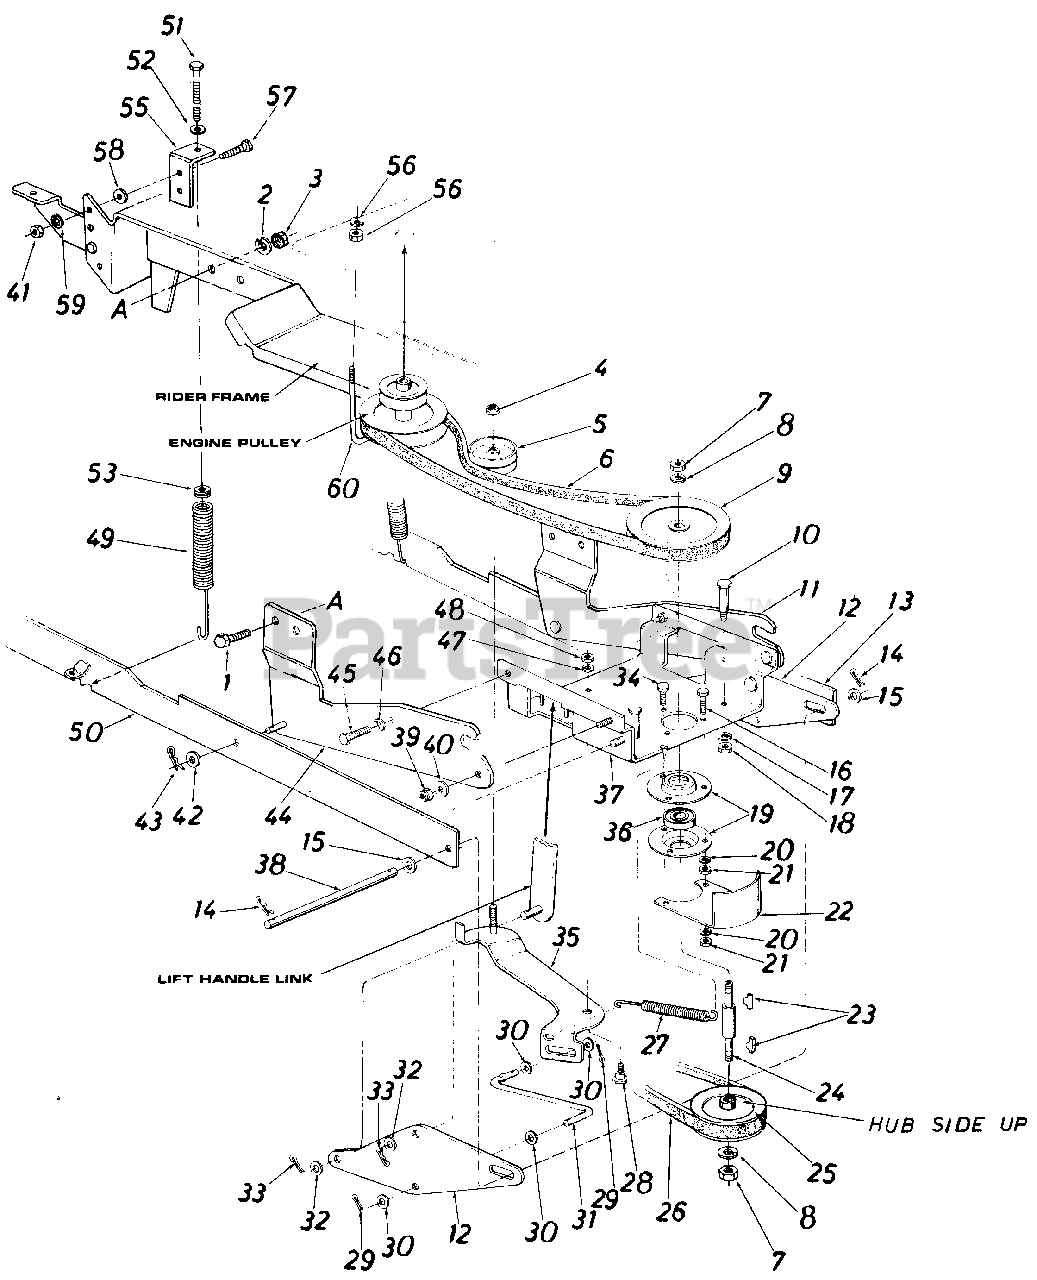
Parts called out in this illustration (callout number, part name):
1	Hex Scr. 1/4-28 x .75" Lg. Grade 5
2	L-Wash. 1/4" Scr.*
3	Hex Nut 1/4-2 Thd.*
4	Hex Ins. Jam Nut 3/8-24 Thd.
5	Flat Idler 3.25" O.D.
6	"V"-Belt 1/2 x 49" Lg.
7	Hex Jam Nut 5/8-11 Thd.
8	L-Wash. 5/8" I.D.*
9	6.50" O.D. x 5/8 Pulley
10	ShoulderScrew
11	Channel Supporting Brkt.-R.H.
12	Linkage Brkt.
13	Linkage Arm Ass'y. R. H.
14	Intern. Cotter Pin .500" Dia.*
15	Fl.-Wash.
16	Hex Scr. 5/16-18 x 1.25" Lg. *
17	L.-Wash. 3/8" Scr.*
18	Hex Nut 3/8-16 Thd.*
19	Bearing Housing
20	L.-Wash. 5/16" Scr.*
21	Hex Nut 5/16-18 Thd.*
24	Pulley Spindle
25	4.00 O.D. x 5/8 Pulley
26	"V"-Belt 1/2 x 85.2" Lg.
27	Extension Spring
28	Shoulder Screw
29	Cotter Pin 3/32" Dia. x 1.00*
30	F l-Wash.
31	Control Rod
32	Fl-Wash.
33	Inter. Cotter Pin .500" Dia.*
34	Hex Sems Scr. 5/16-18 x 1.0" Lg.
35	Clutch Idler Brkt. Ass'y.
36	Ball Bearing
37	Channel Ass'y.
38	Lift Handle Shaft
39	Hex Ins. L-Nut 3/8-16 Thd.
40	F l.-Wash.
41	Hex Nut 1/4-20 Thd.*
42	F l.-Wash.
43	Intern. Cotter Pin .500" Dia.*
44	Channel Supporting Brkt.-L.H.
45	Hex Scr. 3/8-16 x 1.00" Lg. *
46	L.-Wash. 3/8" Scr.*
47	L.-Wash. 5/16" Scr.*
48	Hex Nut 5/16-18 Thd.*
49	Helper Spring
50	Linkage Arm Ass'y.-L.H.
51	Hex Scr. 5/16-18 x 2.0" Lg. Special
52	Fl.-Wash. 5/16" Scr.*
53	Spring Insert
57	Hex Bolt 1/4-20 x .75" Lg. *
58	Fl.-Wash..264" I.D.
59	L.-Wash. 1/4" I.D.*
60	J-Bolt 5/16-18
